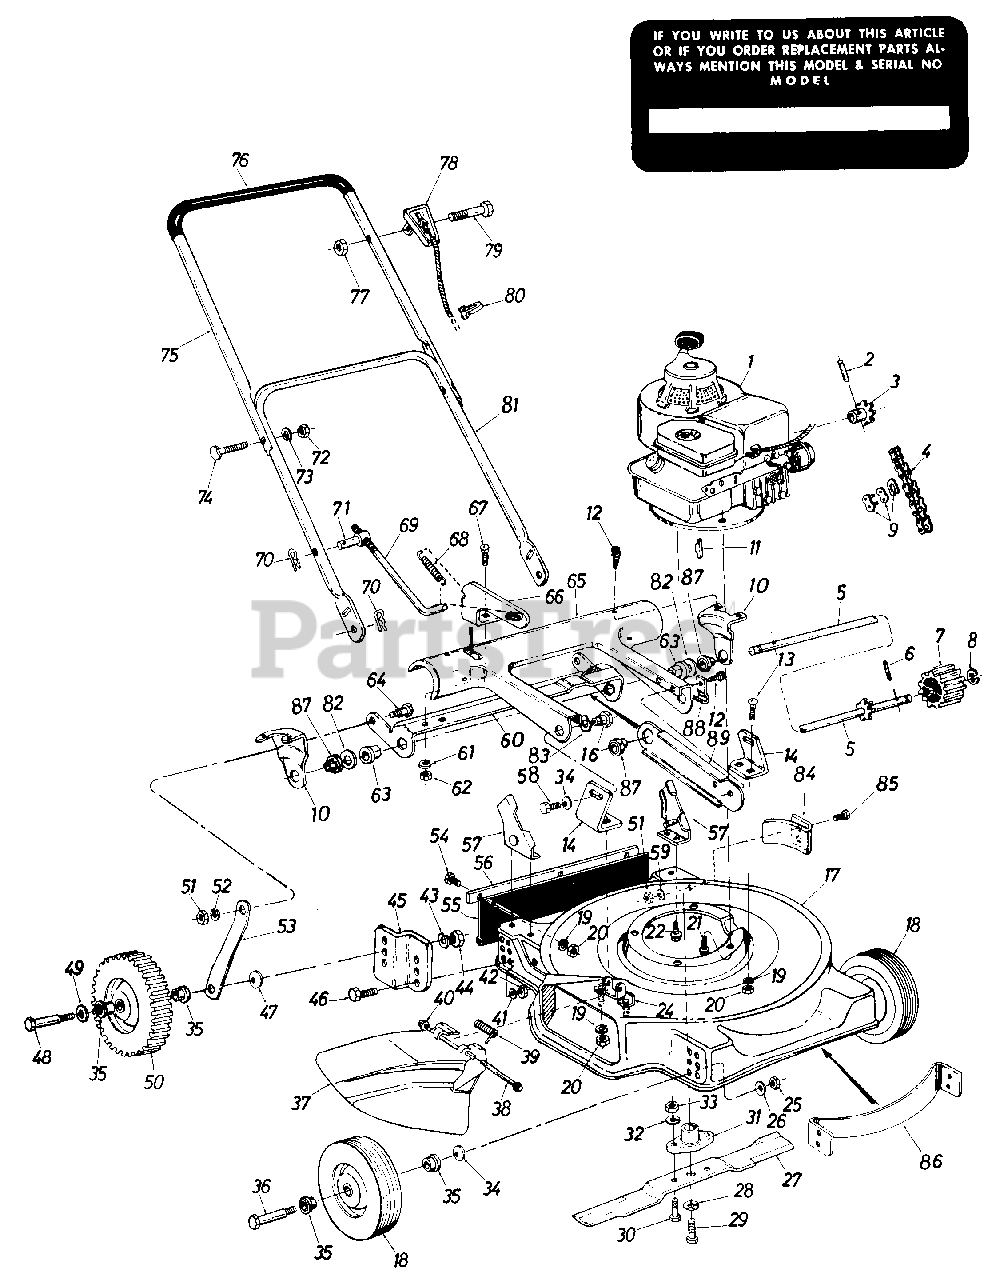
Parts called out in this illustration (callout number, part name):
1	Engine
2	Spiral Pin 3/16 Dia. x 1.00 Lg.
3	10 Tooth Sprocket Ass'y.
4	#48 Chain 1/2" Pitch 46 Links
5	Pinion Shaft w/7 Tooth Sprocket
6	Spiral Pin 3/16 Dia. x 1.25 Lg.
7	Drive Pinion 13 Teeth
8	E-Ring for .500 Dia. Shaft
9	#48 Master Link
10	Axle Brkt.
11	No. 6 Hi-Pro Key 5/32 x .62 Dia.
12	Hex AB-Tap Scr. 1/4 x 5/8" Lg.
13	Carriage Bolt 1/4-20 x .50" Lg.
14	Pivot Bracket
16	Shld. Nut .625 Dia. x .165 Lg.
17	20" Deck Ass'y.
18	Wheel Ass'y. - 7 x 1.75
19	L-Wash. 1/4" I.D.
20	Hex Nut 1/4-20 Thd.
21	Hex Wash. Hd. TT-Tap Scr. 3/8-16 x .88" Lg.
22	Hex Wash. Hd. B-Tap Scr. 5/16-18 x .50" Lg.
24	Deflector Hinge Plate Ass'y.
25	Hex Nut 3/8-16 Thd.
26	Bell-Wash. .400 I.D. x .88 O.D. x .06
27	20" Blade
28	L-Wash. 3/8" I.D. - H.D.
29	Hex Bolt 3/8-24 x 1.50" Lg.
30	Hex Bolt 5/16-24 x 1.0" Lg.
31	Blade Adapter
32	L-Wash 5/16" I.D.
33	Hex Nut 5/16-24 Thd.
34	Bell-Wash. .400 I.D. x .88 O.D. x .06
35	Fortiflex Bearing
36	Shld. Bolt .498 Dia. x 1.44" Lg.
37	Chute Deflector
38	Hinge Pin 3/16 Dia. x 3.88
39	Torsion Spring
40	Push Cap .19 Rod
41	Bell-Wash. .400 I.D. x .88 O.D. x .06
42	Hex Nut 3/8-16 Thd.
43	L-Wash. 1/4" I.D.
44	Hex Nut 3/8-16 Thd.
45	Wheel Brkt.
46	Hex Bolt 3/8-16 x .75" Lg.
47	Bell-Wash. .400 I.D. x .88 O.D. x .06
48	Shld. Bolt .498 Dia. x 1.64" Lg.
49	Fl-Wash. .531 I.D. x .93 O.D. x .10 Thk.
50	Wheel Ass'y. Comp. 8 x 1.75
51	Hex Nut 5/16-18 Thd.
52	L-Wash. 1/4" I.D.
53	Link 4.57 x .88
54	Hex Bolt 1/4-20 x .62" Lg.
55	Flap Ass'y.
56	Retaining Strip
57	Handle Brkt. R.H.
58	Hex Bolt 3/8-16 x .50" Lg.
59	Bell-Wash. .33 I.D. x .860 O.D. x .060
60	Cam
61	L-Wash. 1/4" I.D.
62	Hex Nut 1/4-20 Thd.
63	Hex Bearing
64	Shld. Bolt .437 Dia. x 1.62 Lg.
65	20" Pinion Pivot Cover
66	Engagement Arm
67	Carriage Bolt
68	Extension Spring
69	Engagement Rod
70	Hairpin Cotter
72	Hex Nut 5/16-18 Thd.
73	L-Wash 5/16" I.D.
74	Curved Hd. Carriage Bolt 5/16-18 x 1.38" Lg.
75	Upper Handle
77	Hex L-Nut 1/4-20 Thd.
78	Throttle Control Ass'y. Comp.
79	Hex Bolt 1/4-20 x 1.50" Lg.
80	Cable Tie
81	Lower Handle
82	Fl-Wash. .53 I.D. x .050 Thk.
83	Spring Wash. .625 I.D. x .885 O.D.x .015
84	Rear Baffle
85	Hex Bolt 5/16-18 x .62" Lg.
86	Front Baffle (270)
87	Ball Bearing
88	Cable Clip
89	Bearing Support
